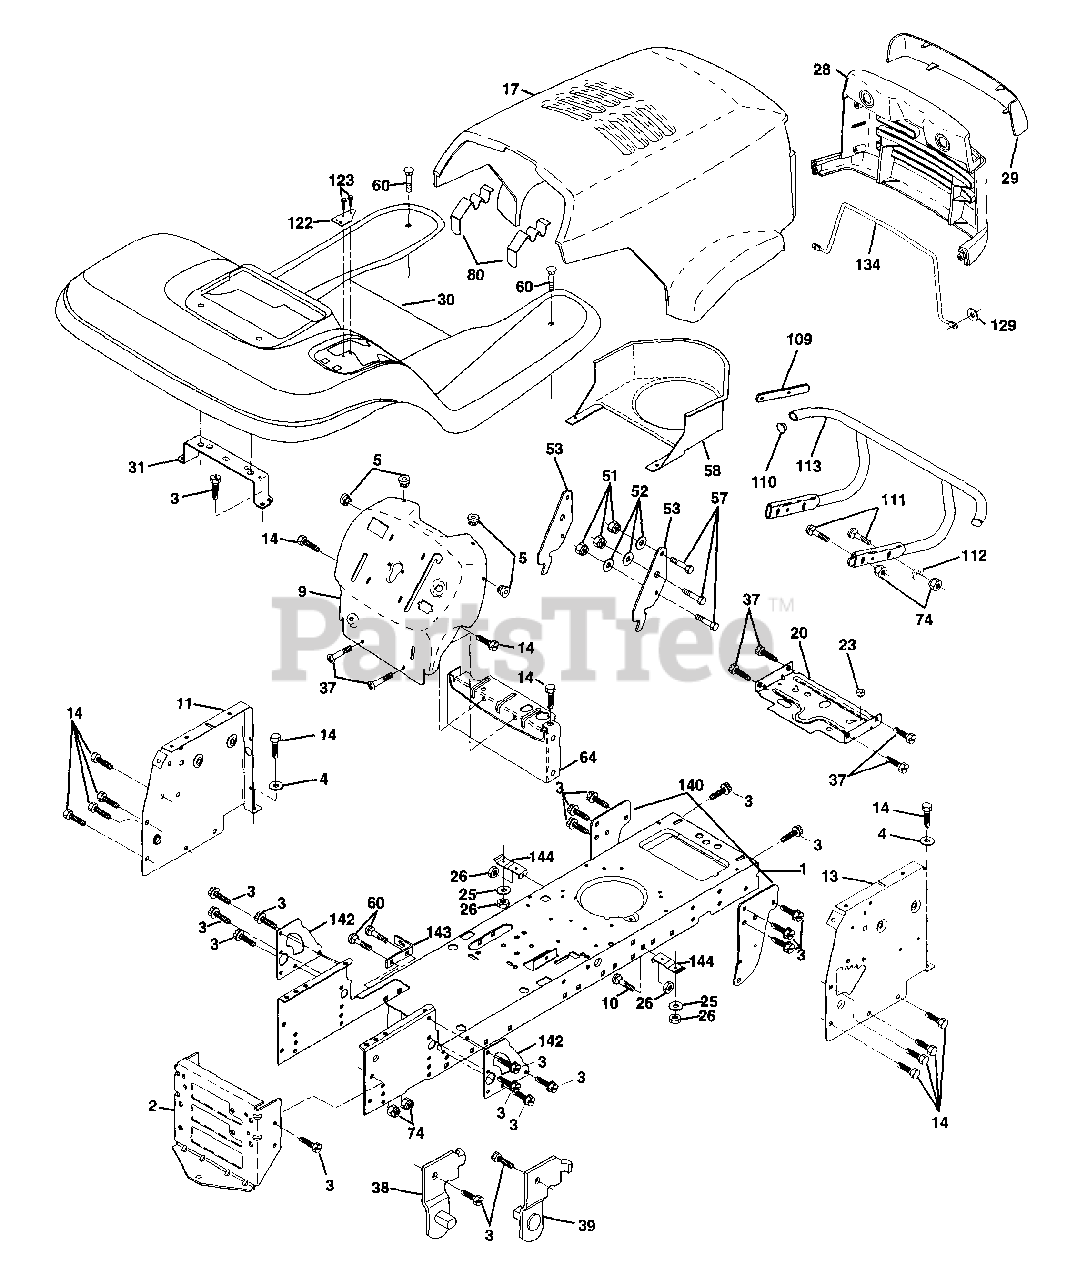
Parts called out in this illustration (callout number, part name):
1	Chassis Weldment
2	Drawbar, Stretch
3	Screw Thdrol 3/8-16x3/4 Ty-tt
4	Washer 13/32 x 3/4 x 16 Ga.
5	Bumper Hood/Dash
9	Dash P/L M, Slkscr Elec N/A N/Hm
10	Bolt Carriage 3/8-16 x 1
11	Panel Dash Lh
13	Panel Dash Rh
14	Screw Thdrol 3/8-16x1/2 Ty-tt
17	Hood LT/PL Husqvarna
20	Plate Mtg Battery Fuel Tank Fr
25	Washer 13/32 X 13/16 X 12 Ga
26	Nut Lock Hex W/Ins 3/8-16 Unc
28	Grille ET/PL Husqvarna
29	Lens ET/PL Husqvarna
30	Fender Footrest STLT Pnt
31	Bracket Support Fender
37	Screw Thdrol 6/16-18 x 1/2 TYT
38	Bracket, Asm. Pivot, L.H., Mower Rear
39	Bracket, Asm. Pivot, R.H., Mower Rear
51	Nut Lock Hex W/Ins 1/4-20
52	Washer 9/32 x 7/8 x 16 Ga.
53	Bracket Pnt. Pick off LT/PL Husqvarna
57	Bolt Hex 1/4-20 x 3/4
58	Air Duct Engine P/L
60	Bolt Rdhd Sqnk 3/8-16unc x 3/4
64	Dash Lower STLT
74	Nut Crownlock 3/8-16 UNC
80	Latch Hood Plm Husqvarna
109	Bracket Extension, Bumper
110	Plug, Plastic
111	Bolt, Rdhd 3/8-16 UNC x 1-1/2
112	Washer, 13/32 x 13/16 x 16 Ga.
113	Bumper Asm
129	Washer 9/32 x 5/8 x 16 Ga.
134	Rod Support Hood LT/PL Husq.
140	Bracket Chassis Front 7 Ga.
142	Plate Reinforcement STLT
143	Bracket Swaybar Chassis
144	Bracket Pnt Footrest STLT
146	Screw Torx Hd Thd 5/16-18 UN-2A
